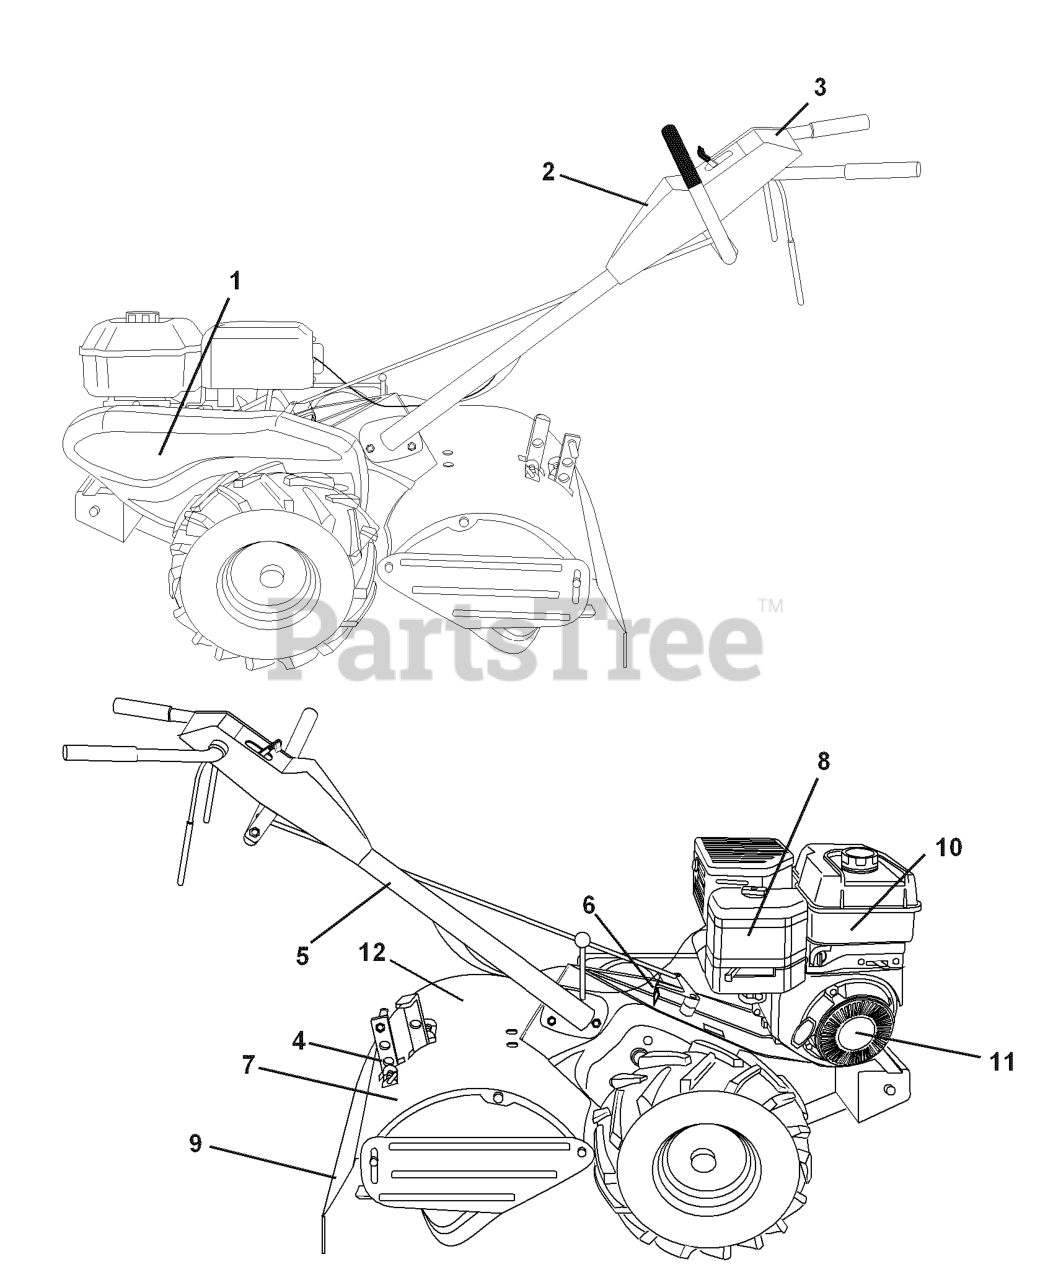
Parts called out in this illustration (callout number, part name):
1	DECAL.BELT.GUARD.HUSQ.TILLER
2	DECAL,HUSQVARNA,CONTROL PANEL
3	DECAL.CONSOLE.DRT.HU
4	DECAL.SHIELD.TN.17.D
5	DECAL TI (2 2)
6	DECAL.SHIFT.INDICATOR.DRT
7	DECAL.REVERSE.HUSQ
8	DECAL.B&S.900.A/C.REF.277024
9	DECAL.DRT.WARN.ENG/F
10	DECAL.B&S.900.TANK.REF.276991
11	DECAL, REWIND STARTER, B&S
12	DECAL.FORWARD.HUSQ
12	Manual, Owner's
